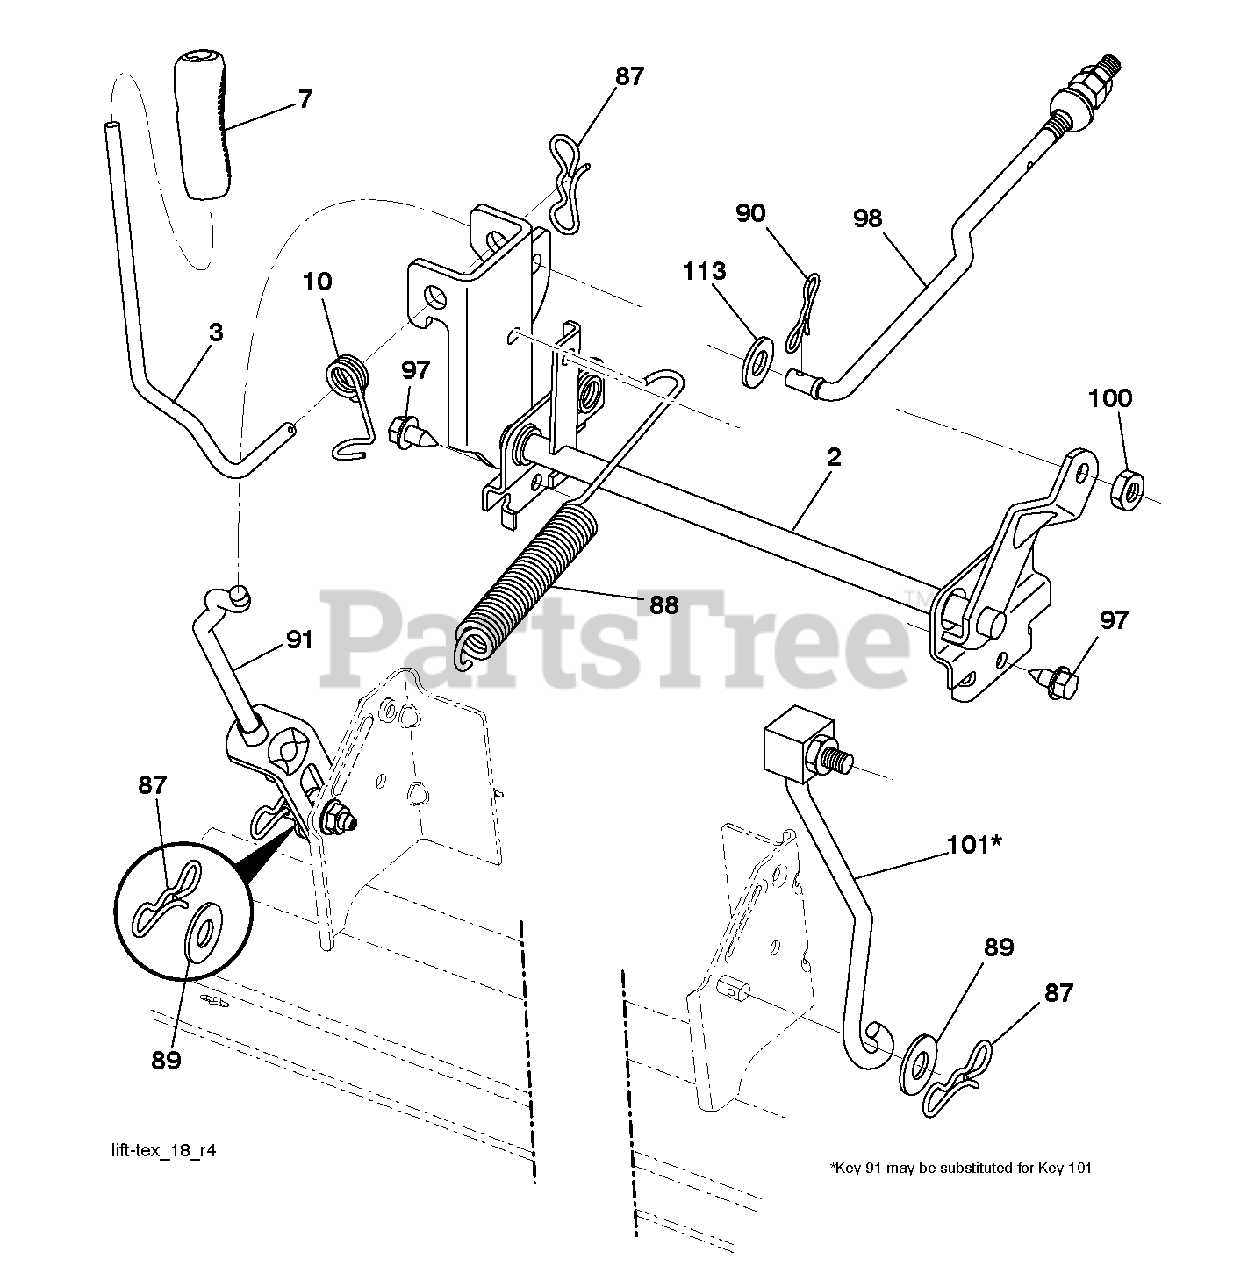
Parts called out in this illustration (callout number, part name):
2	SHAFT.ASM.CROSS.LIFT
3	LEVER.LIFT.HANDLE.LT
7	GRIP.HANDLE.LIFT.PVC.BLACK
10	SPRING.TORSION.LIFT.HANDLE
87	PIN.COTTER.7/16.BOW TI
88	SPRING.LIFT.ASSIST
89	WASHER.CLEAR.ZINC
90	PIN.COTTER.5/16.BOW TI
91	LINK.ASM.LIFT.REAR
97	SCREW, 3/8-16X3/4
98	LINK.ASM.SUSP.FRONT.MWR.10.5
100	LOCKNUT
101	LINK.ASM.LIFT.FIXE.38/42/46"
